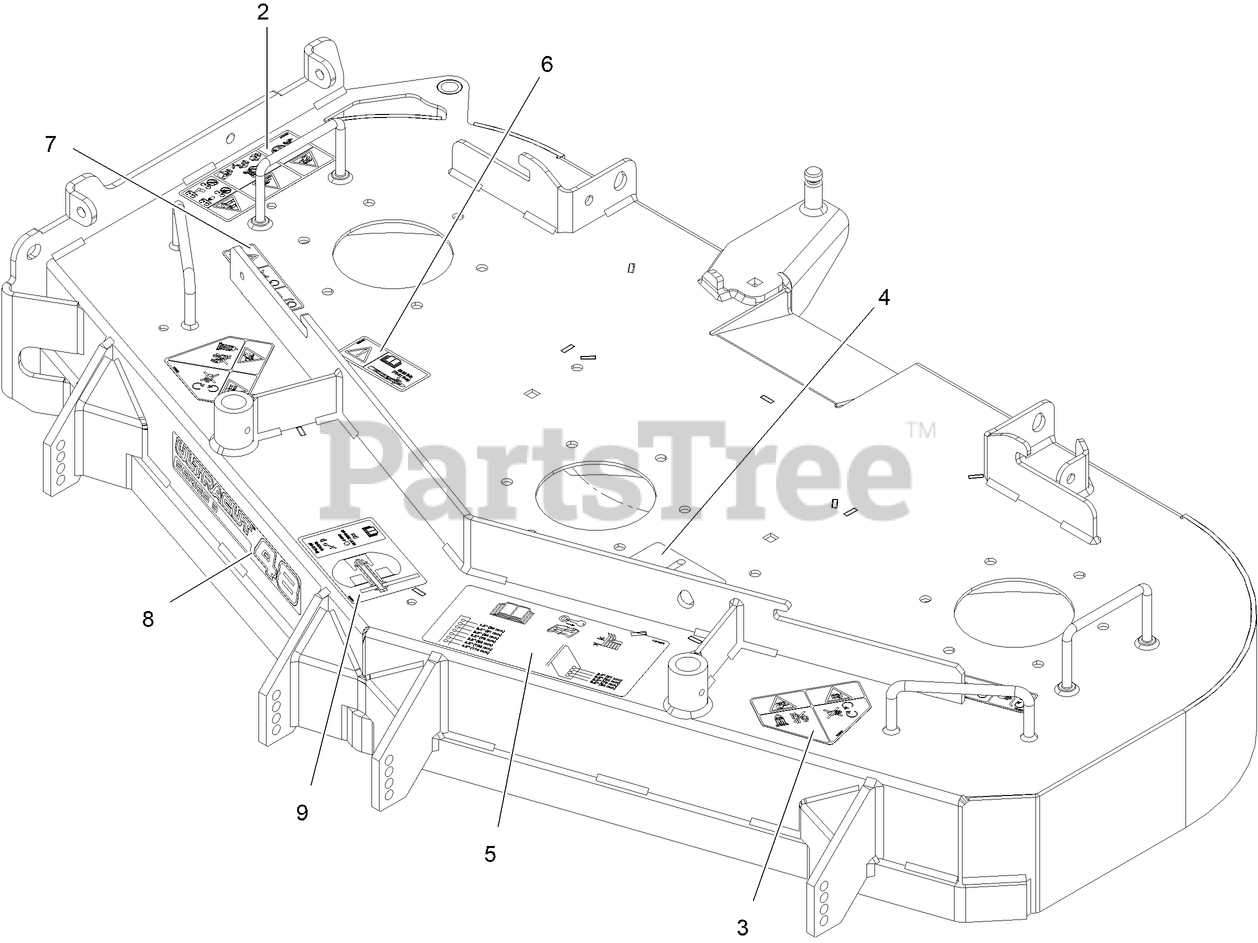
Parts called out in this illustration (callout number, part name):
2	DECAL-WARNING THROWN OBJ
3	DECAL-DANGER
4	DECAL-BELT ROUTING
5	DECAL-ANTI-SCALP
6	DECAL-TORQUE, BOLT
7	DECAL-COVER, MISSING
8	DECAL-ULTRACUT 48 SERIES 3
9	DECAL-ROLLER MOUNTING
